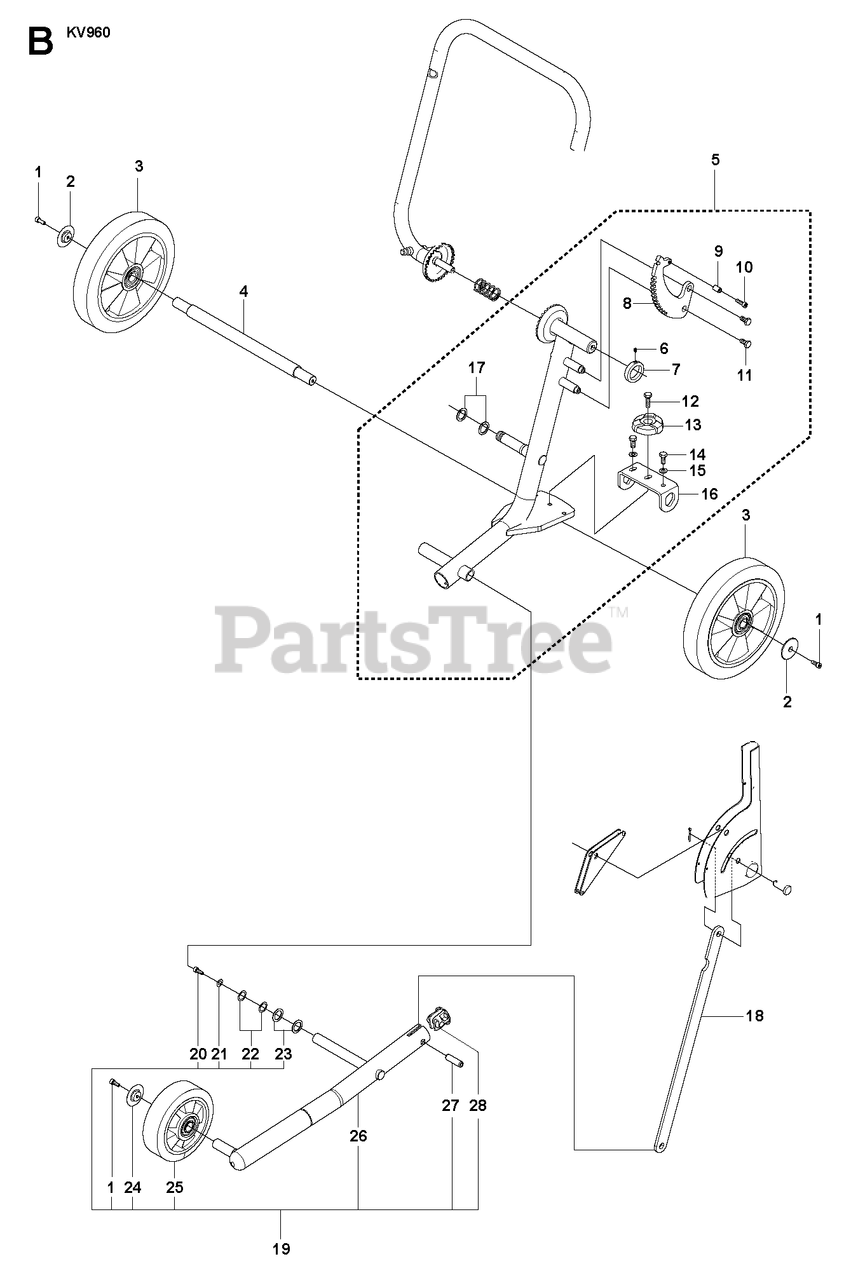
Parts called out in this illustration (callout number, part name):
3	WHEEL
10	SCREW IHSCM
11	SCREW EHHM
13	TURNING KNOB
19	FRAMEIncl. 1, 18 - 26
20	SCREW EHHM
